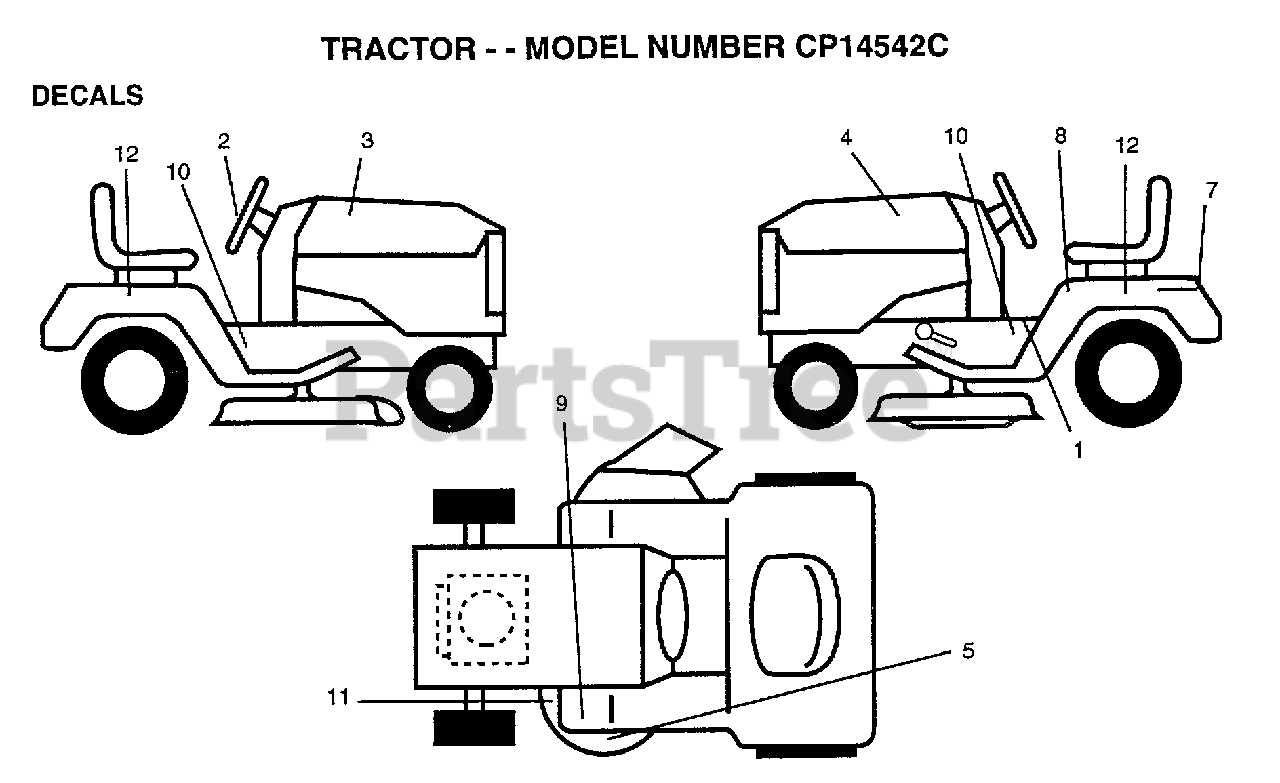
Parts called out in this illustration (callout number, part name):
3	DECAL.HD.RH.CP.
4	DECAL.HD.LH.CP.
7	DECAL.BTRY.DANGER
8	DECAL
10	CHASSIS DECAL
11	DECAL
12	DECAL.FEND.QUICK.
